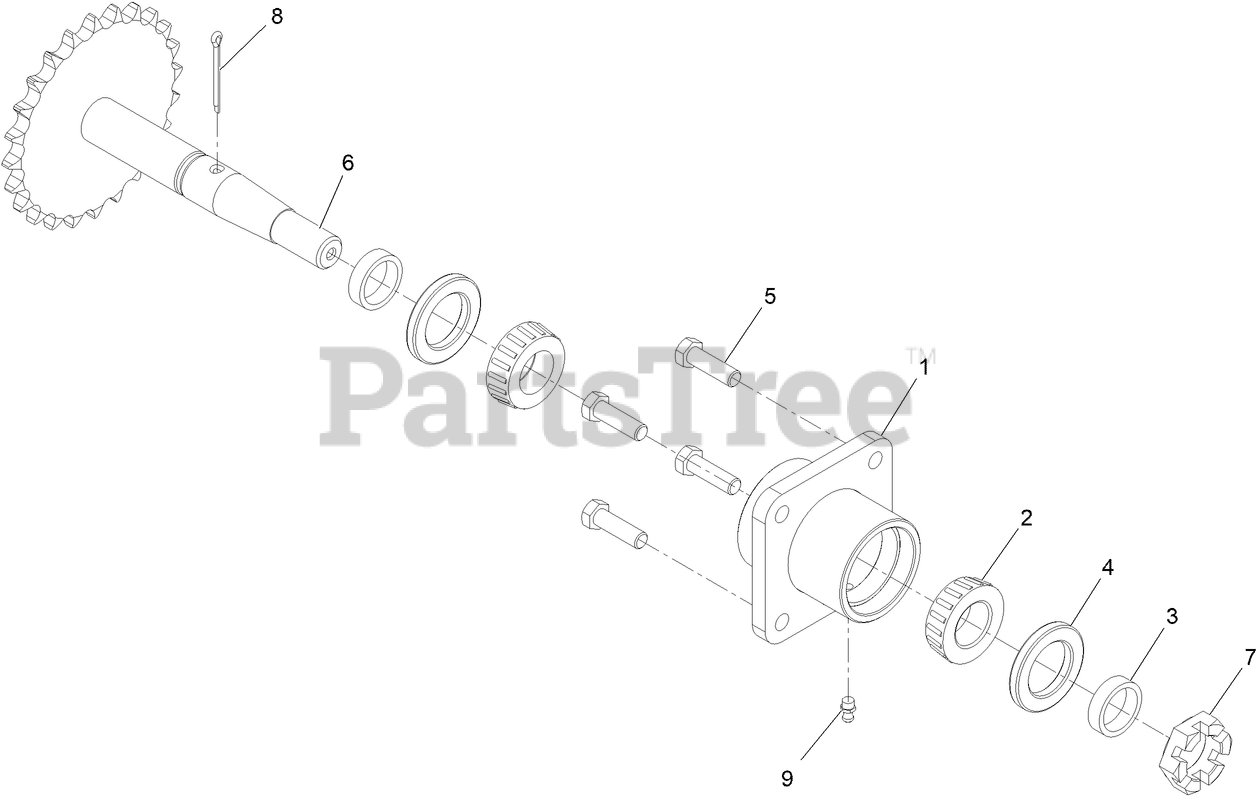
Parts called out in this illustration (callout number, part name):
1	MOUNT-BEARING, WHEEL
2	Cone-Bearing Tapered Roller
4	SEAL-GREASE
5	SCREW-HH
7	Nut-Jam, Slot
8	PIN-COTTER
9	FITTING-GREASE
